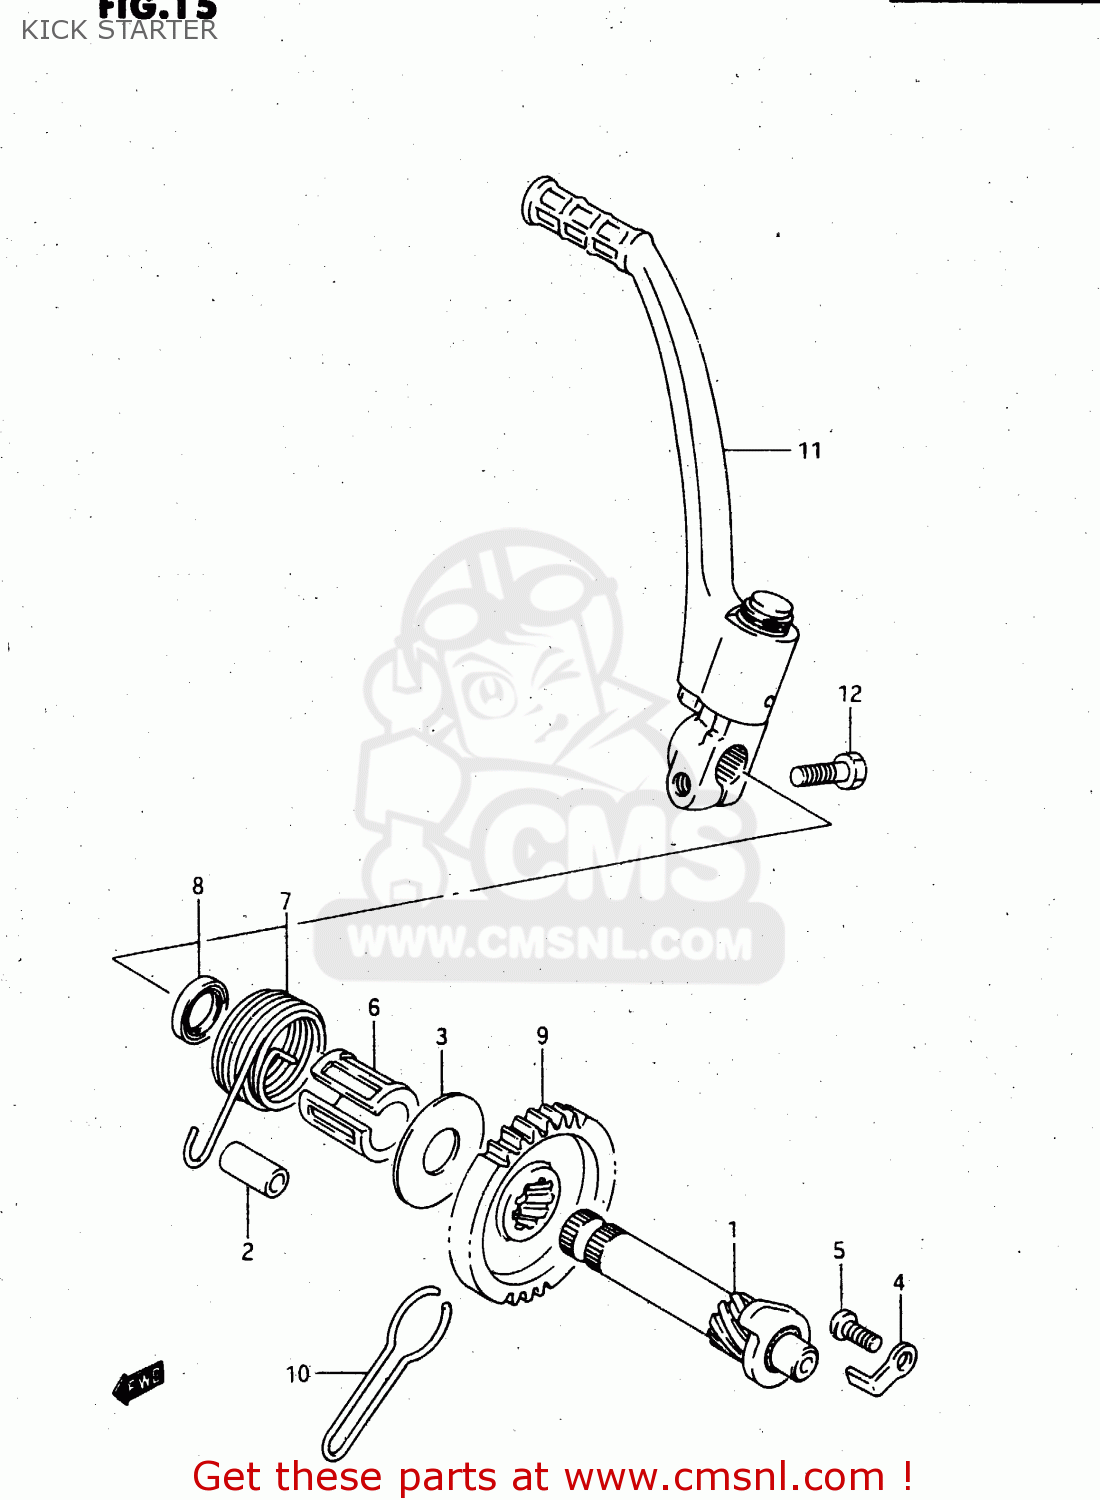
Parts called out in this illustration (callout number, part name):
1	SHAFT,KICK STARTER
2	SPACER(6.5X10.5X22.5)
3	WASHER
4	STOPPER,KICK STARTER
5	SCREW
6	GUIDE,KICK STARTER SFT SPRING
7	SPRING
8	SEAL,OIL(16X24X5)
9	GEAR,KICK DRIV
10	SPRING,KICK STARTER RETAINER
11	LEVER ASSY,KICK STARTER
12	BOLT
